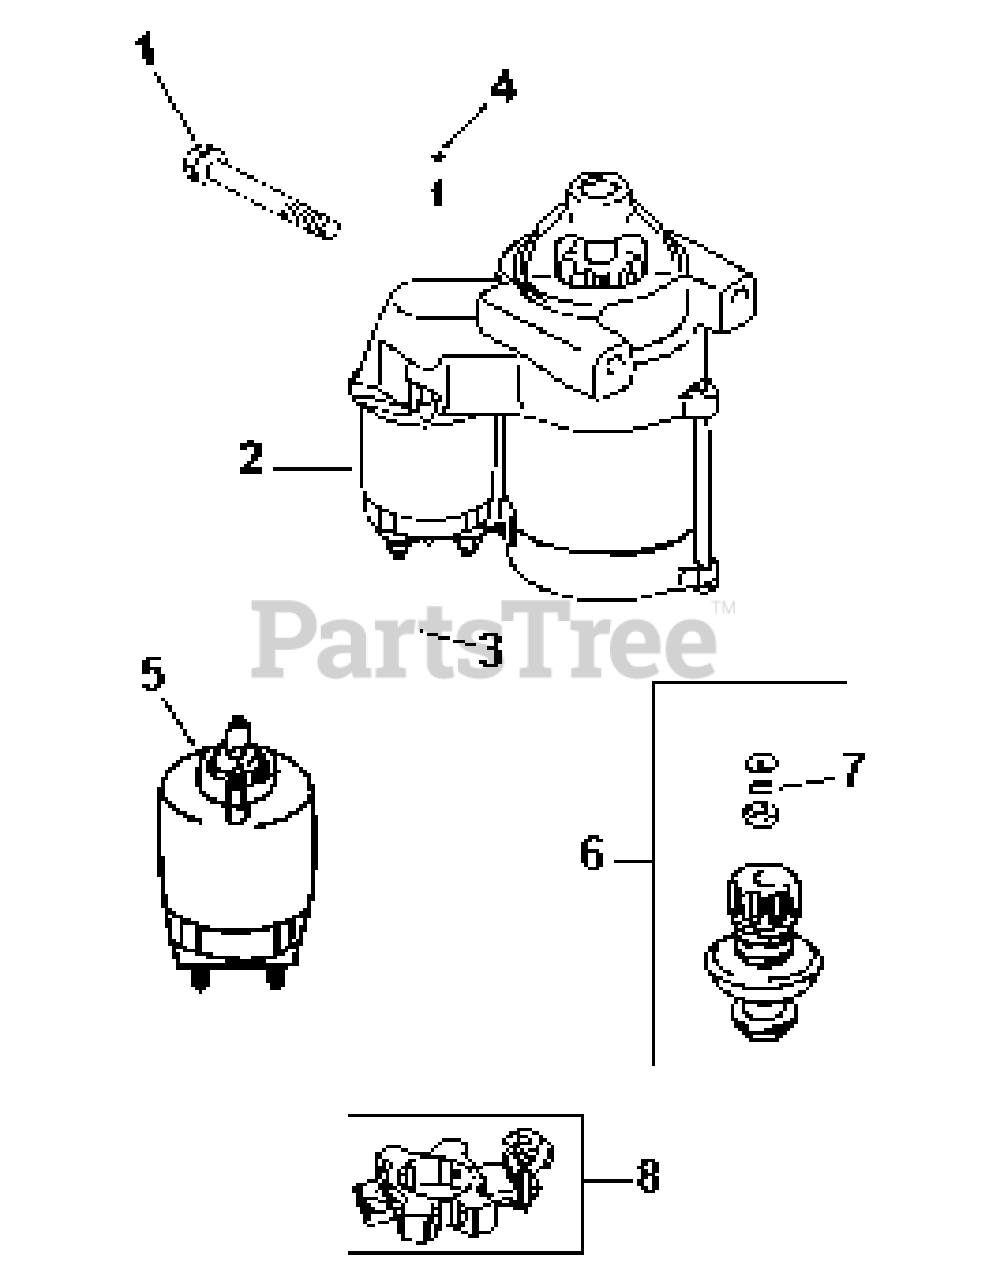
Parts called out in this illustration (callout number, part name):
1	Hex Flange Screw (M8 x 1.25 x 80)
2	Solenoid Shift Starter
3	Hex Flange Nut (M8 x 1.25)
4	External Torx Head Screw
5	Solenoid Kit
6	Starter Pinion Kit
